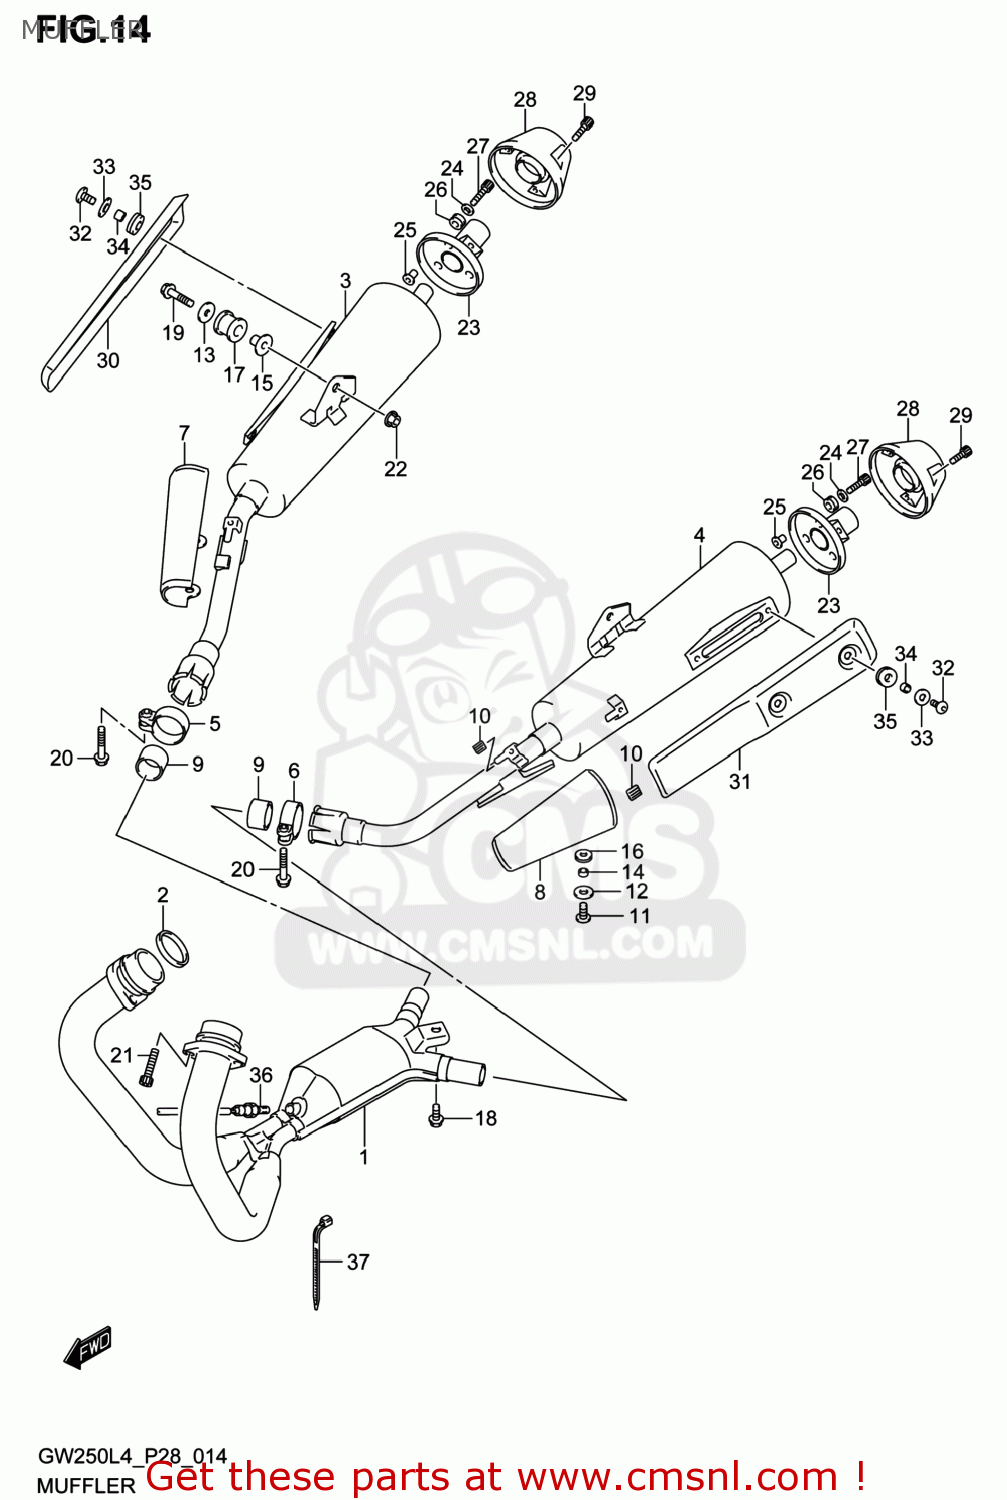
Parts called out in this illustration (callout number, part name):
1	EXHAUST
2	GASKET,EXHAUST PIPE (NAS)
3	MUFFLER,R
4	MUFFLER,L
5	CLAMP,MUFFLER CONNECTOR,R
6	CLAMP,MUFFLER CONNECTOR,L
7	COVER,MUFFLER FR,R
8	COVER,MUFFLER FR,L
9	CONNECTOR,JOINT
10	GROMMET
11	SCREW(6X16)
12	WASHER(6.5X18.0X1.0)
13	WASHER(8.5X30X1.6)
14	SPACER(6.5X9X5)
15	SPACER
16	CUSHION
17	CUSHION
18	BOLT
19	BOLT
20	BOLT
21	BOLT
22	NUT
23	STAY,MUFFLER RR COVER
24	WASHER(6.5X18X1)
25	SPACER(6.2X8.4X10.9)
26	CUSHION
27	BOLT
28	COVER,MUFFLER RR
29	BOLT
30	COVER,MUFFLER BODY,R
31	COVER,MUFFLER BODY,L
32	SCREW(6X16)
33	WASHER(6.5X18.0X1.0)
34	SPACER(6.5X9X5)
35	CUSHION
36	SENSOR,OXYGEN
37	CLAMP,WIRING HARNESS
